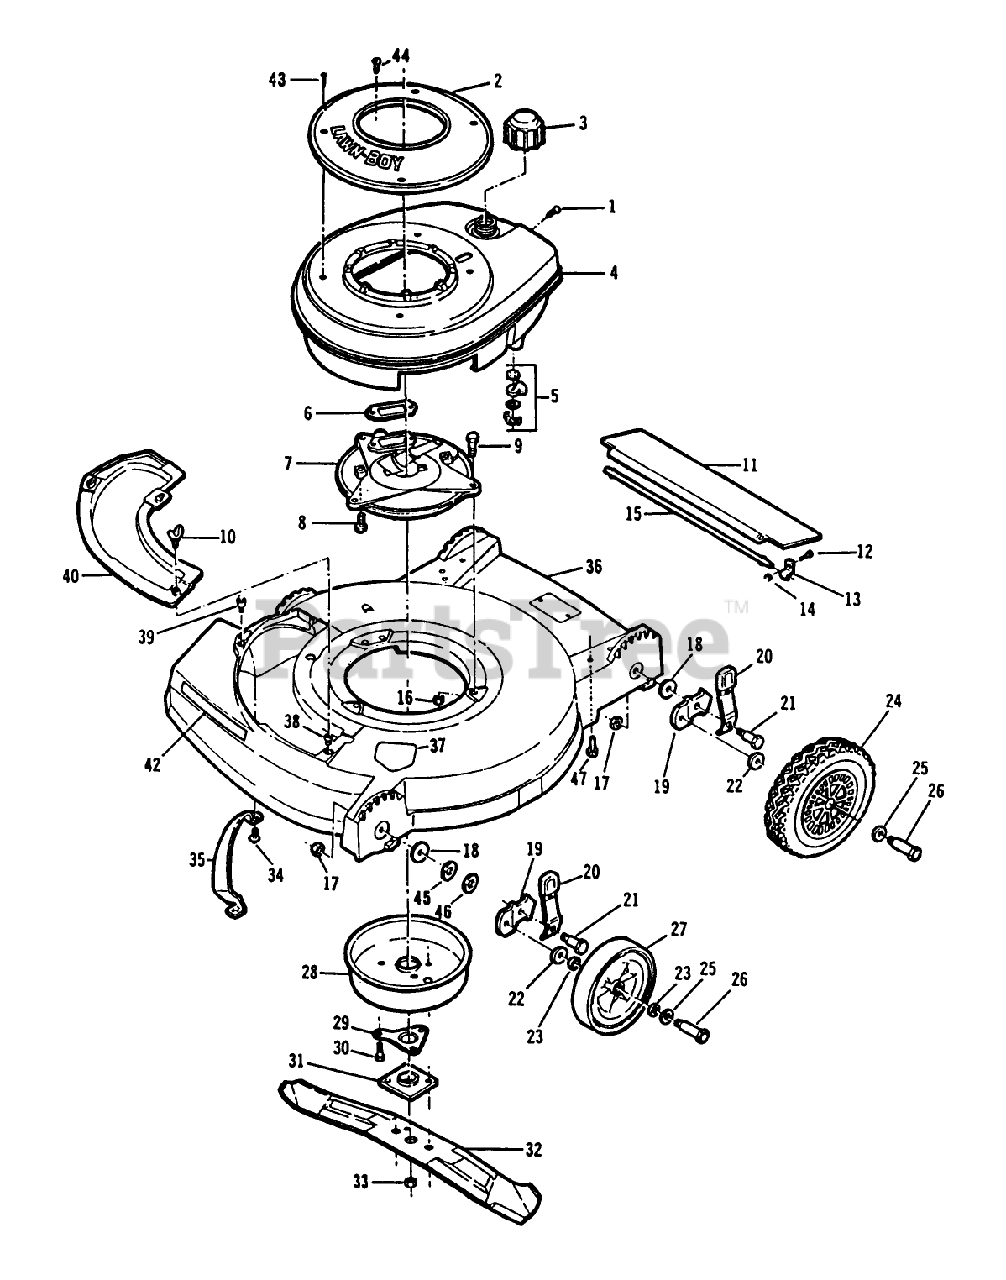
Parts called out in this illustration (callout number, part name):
1	SCREW S
3	FUEL CAP & INSERT
5	SHUT OFF VALVE KIT
7	PLATE F
8	SCREW V
9	SCREW-HH
10	WING SCREW LAWRE
13	CLAMP ROD KMC
14	LOCKNUT E
15	ROD 21" ADVANCE
16	NUT-LOCK F
17	LOCKNUT
18	WASHER
20	SPRING ARM ASM
21	BOLT
22	WASHER WROUGHT
23	WASHER
24	WHEEL&TIRE 8" TRI
25	SPACER
26	BOLT WHEEL
28	MUFFLER COVER F
29	SUPPORT F
30	SCREW
31	PLATE AND COLLAR ASM
33	NUT-BLADE
35	BAR-TOE
43	SCREW - SELF TAPPING
44	SCREW SEMS SM
45	WASHER
46	WASHER
47	SCREW
